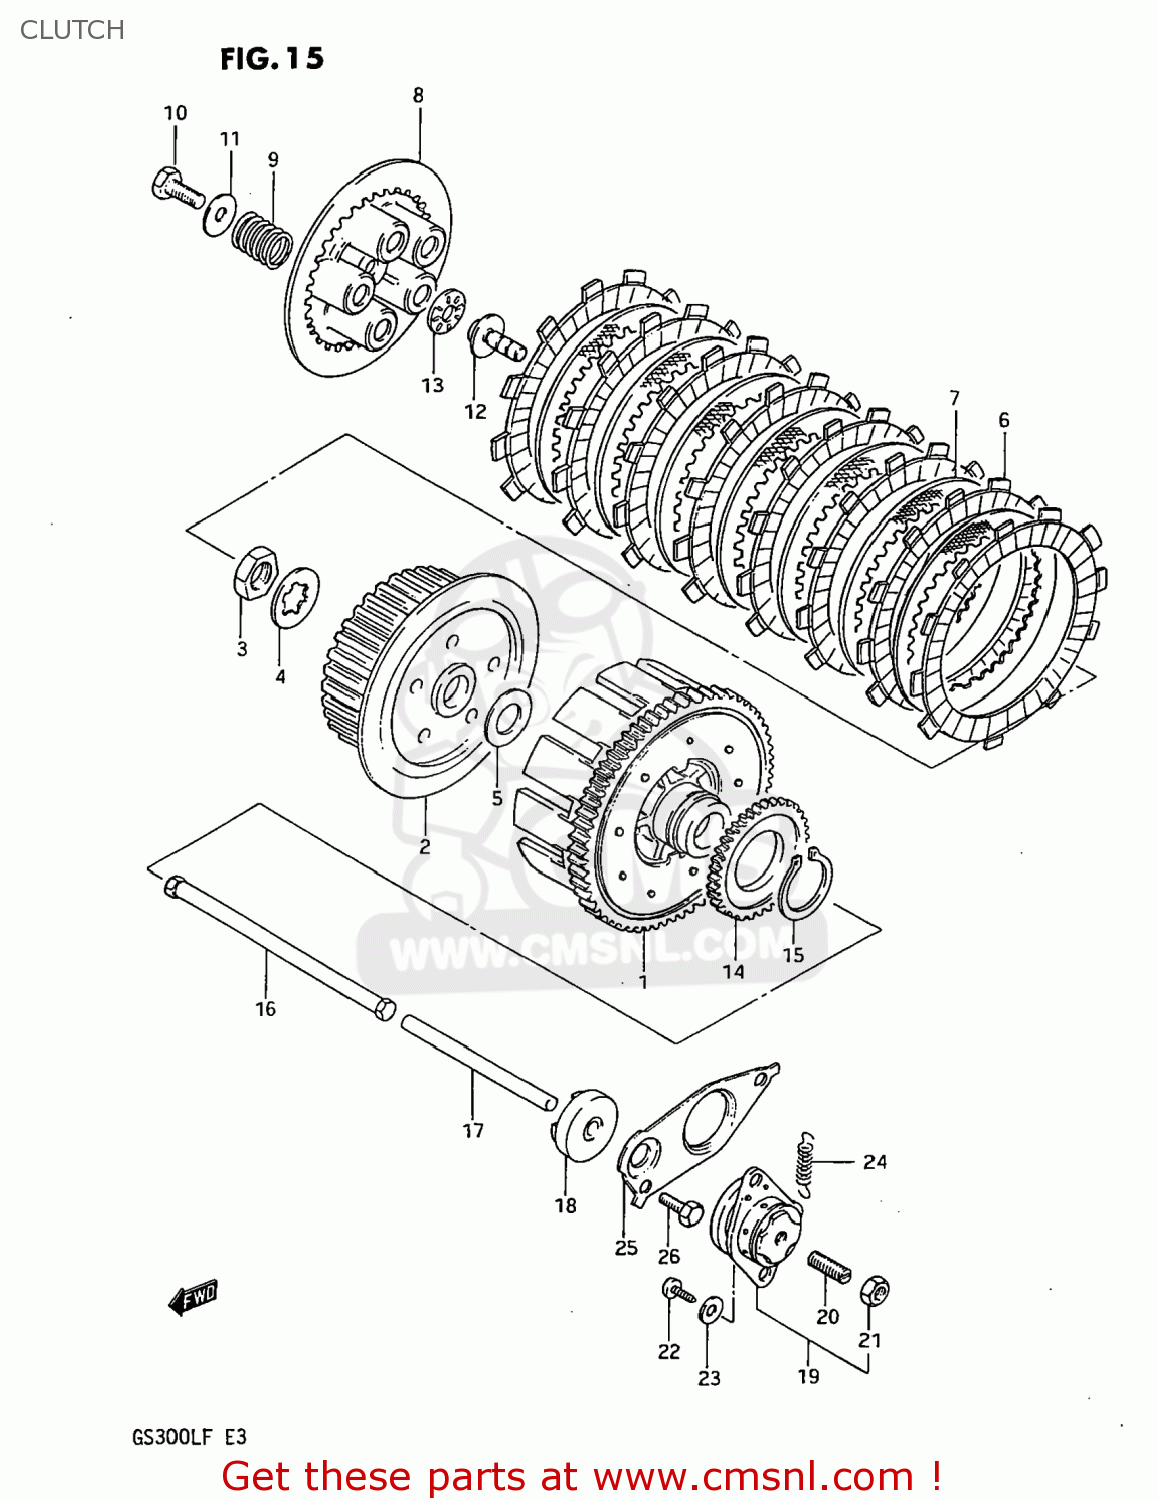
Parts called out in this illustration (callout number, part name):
1	GEAR ASSEMBLY,PRIMARY DRIVE
2	HUB,CLUTCH SLEEVE
3	NUT
4	WASHER
5	WASHER
6	PLATE,CLUTCH DRIVE (MCA)
7	PLATE,CLUTCH DRIVEN (NAS)
8	DISC,CLUTCH PRESSURE
9	SPRING
10	BOLT(5X16)
11	WASHER (5.5X16X1.2)
12	ROD,CLUTCH RELEASE
13	BEARING(10X22X2.8)
14	GEAR,OIL PUMP DRIVE
15	CIRCLIP
16	ROD,CLUTCH PUSH
17	ROD,CLUTCH PUSH
18	SEAL,OIL(6X31X10)
19	SCREW ASSY,CLUTCH RELEASE
20	SCREW(6X25)
21	NUT 6MM
22	SCREW
23	WASHER
24	SPRING
25	PLATE,CLUTCH PUSH ROD
26	BOLT
